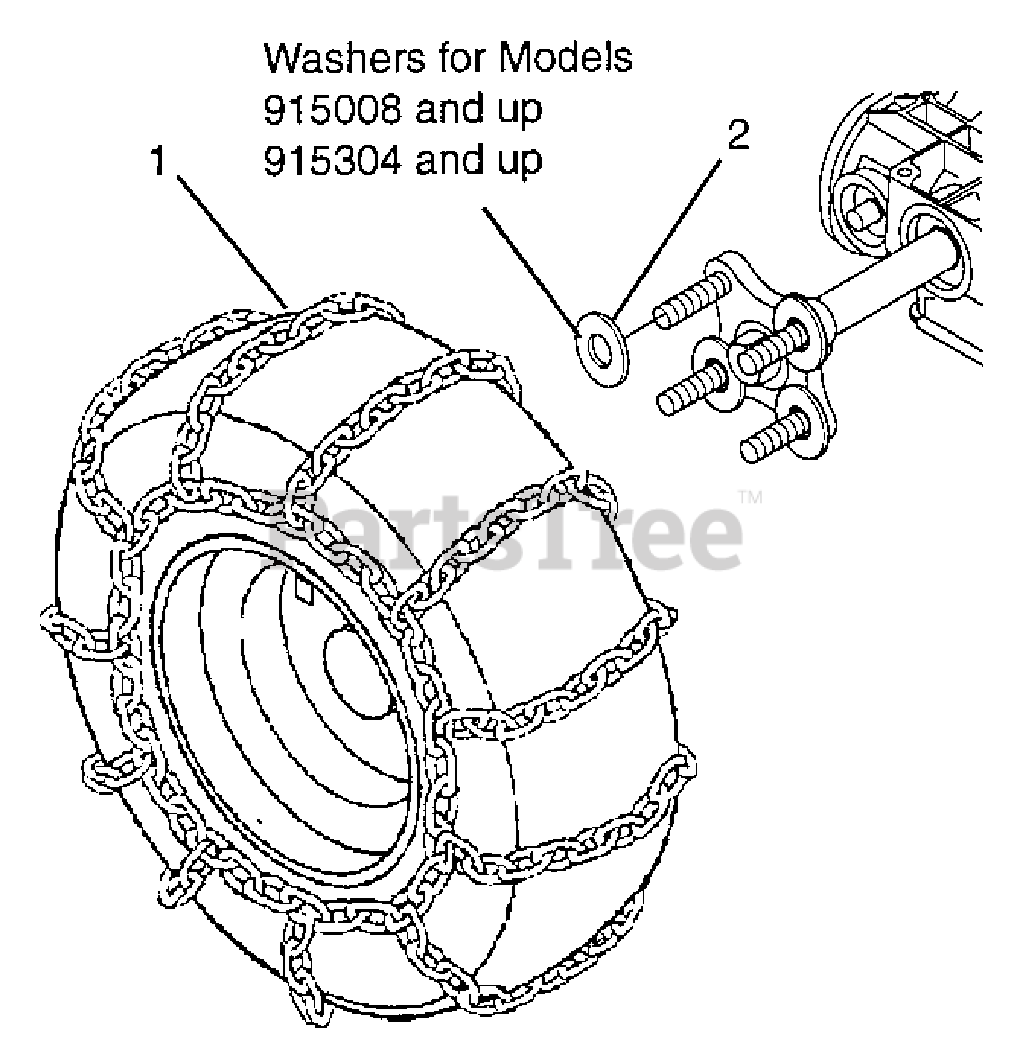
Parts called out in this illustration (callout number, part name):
1	CHAINS, TIRE 18X8.50X8
2	@WSHR-FL-STL.531X1.06X.095YWZC
3	SPACER, WHEEL
4	NUT-LK-CTR .50-20 YWZC
5	STUD .50-20 X .50-13 X 1.75 LG
6	ADHESIVE SEALANT (RED)
